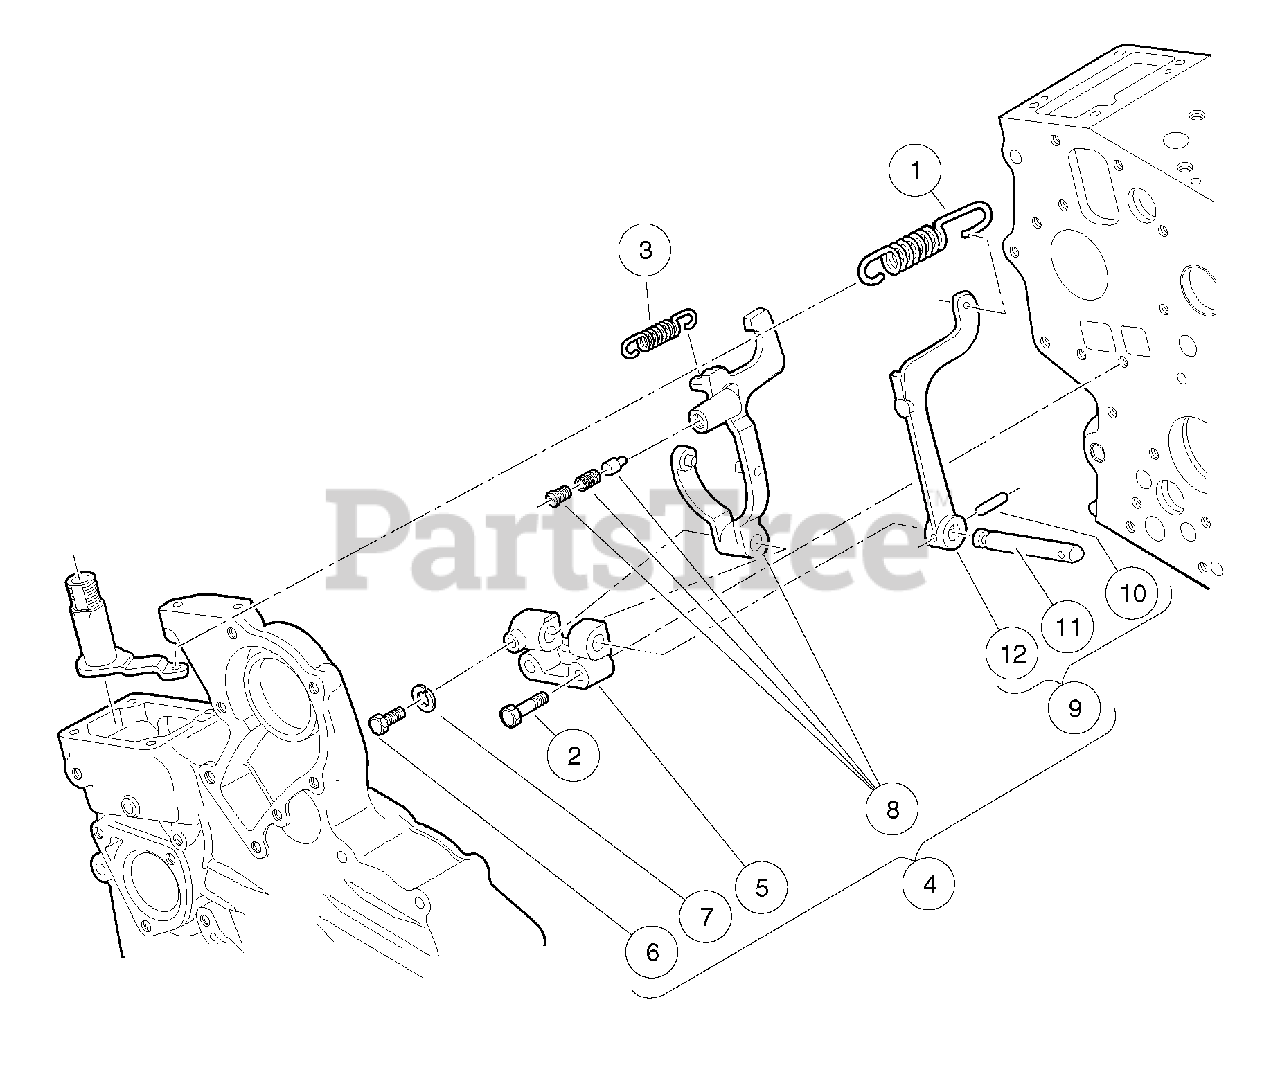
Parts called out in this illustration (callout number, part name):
1	Spring, Governor
2	Bolt, M5 X 0.75 X 25
3	Spring, Start
4	Assembly, Governor Fork
5	Holder, Fork Lever
6	Bolt, M5 X 0.75 X 11
7	Washer, Spring, M5
8	Lever, Fork, Middle, D722 CB
9	Assembly, Governor Fork Level, Lower, D722 CB
10	Pin, Spring
11	Shaft, Fork Lever
12	Lever, Fork, End, D722 CB
